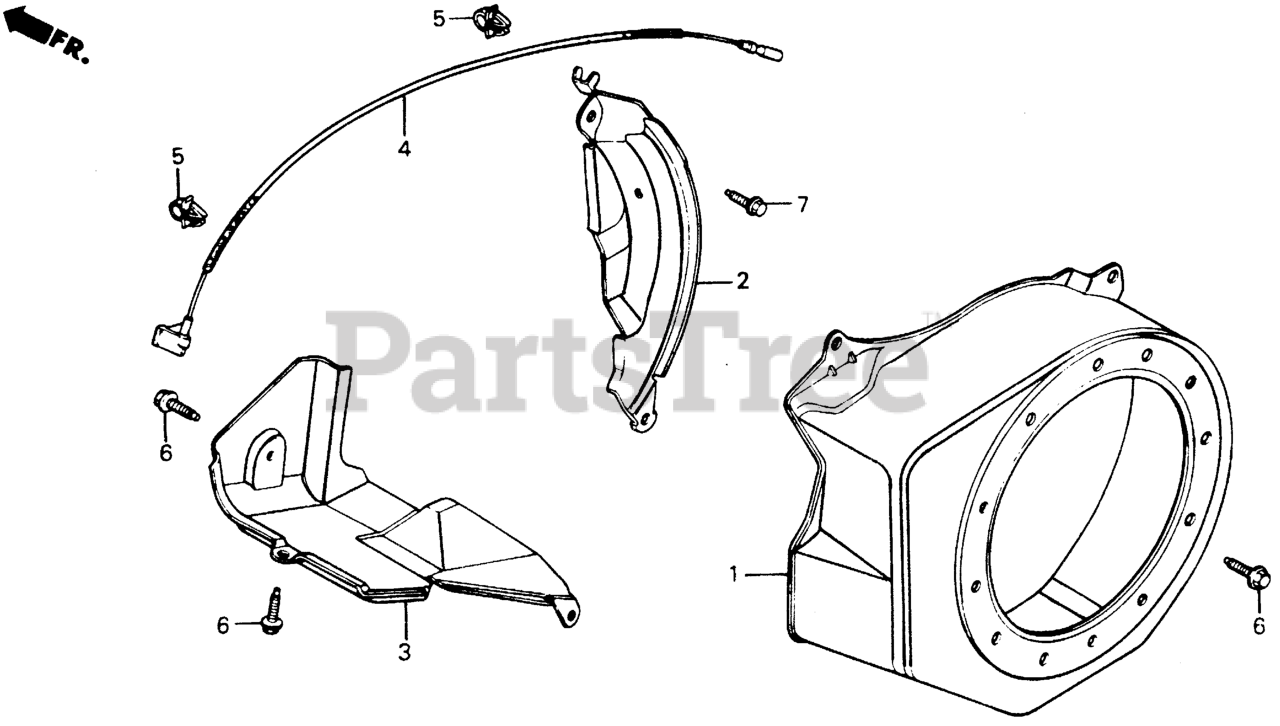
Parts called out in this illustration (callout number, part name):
1	COVER, FAN *B124* (PASTEL GRAY) (NOT AVAILABLE)
3	SHROUD
4	WIRE, STOP SWITCH
5	HOLDER, STOP SWITCH WIRE Use up to Engine SN 2056819.
6	BOLT, FLANGE (6X12) (CT200)
